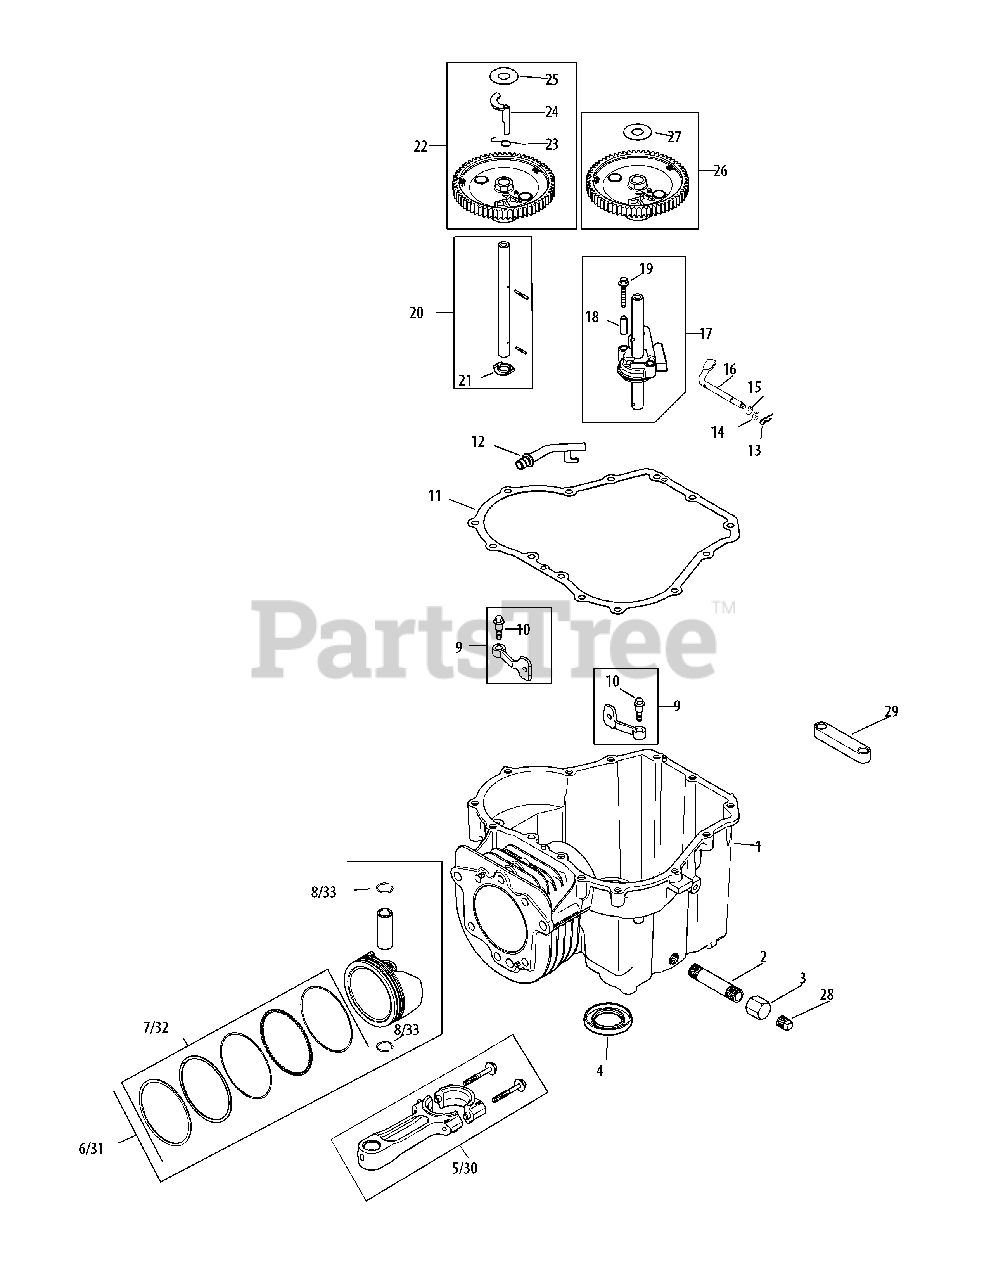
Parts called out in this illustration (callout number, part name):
1	Crankcase (Use: Short Block)
5	Connecting Assembly Rod
6	Piston w/ Ring Set, 94mm (Incl. 7, 8)
8	Piston Pin Retainer
10	Shd. Thd. Frm. Screw, M6 X 1 X 26
12	Drainback Tube
13	Hitch Pin Clip
14	Flat Washer, 6 Mm
15	Flat Washer, 1/4
16	Governor Cross Shaft
17	Oil Pump Ass’y Kit (Incl. 11, 18, 19)
19	Oil Pump Screw
20	Cam Center Shaft Kit (Incl. 21)
21	Thrust Washer
22	Camshaft Ass’y Kit (Incl. 23-25)
25	Thrust -Acr. Washer
26	Camshaft Ass’y Kit (Incl. 27)
27	Thrust -Acr. Washer
28	Square Head Pipe Plug, 3/8
